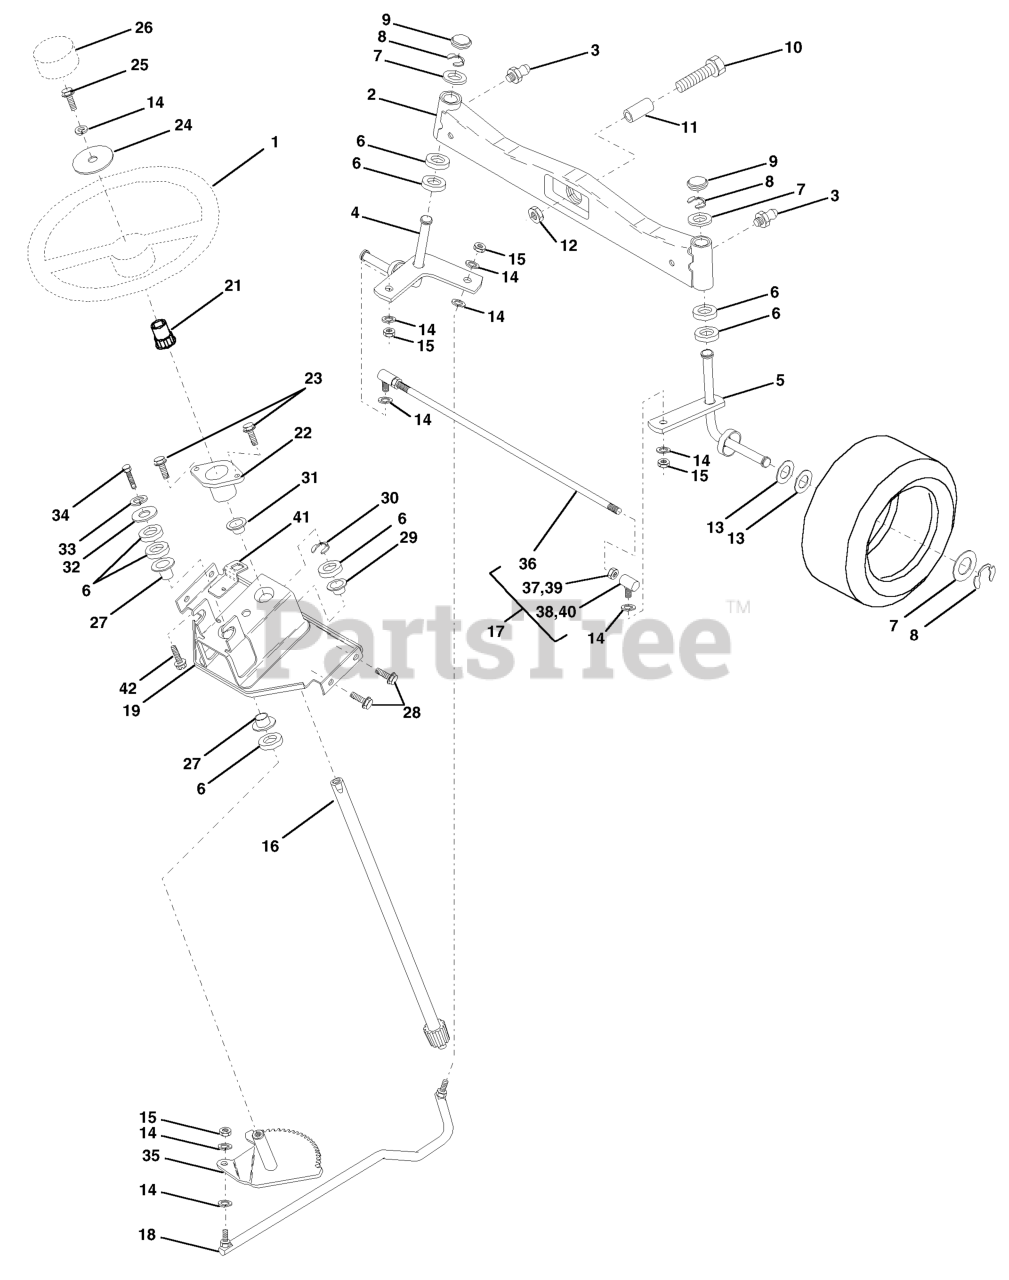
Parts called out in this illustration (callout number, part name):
1	STEERING WHEEL
2	FRONT AXLE ASSY
3	ZERK M
4	SPINDLE ASSY LH
5	SPINDLE ASM RH
6	THRUST WASHER
9	CAP.SPINDLE.BLACK
10	Bolt, Fin Hex 5/8-11 x 2-3/4
11	TUBE, PIVOT AXLE
12	NUT-LOC,FLANGE LT
14	WASHER, LOCK 3/8
15	GRIPCO NUT
16	SHAFT ASM, STEERING
17	ROD ASSY/TIE BALL
18	DRAGLINK-BALL JOINT SOLID
19	SUPPORT ASM., STEERING VGT
21	STEERING WHEEL ADAPTOR
22	BUSHING, STRG. BLK
23	SCREW.TT.#10-32X.5.3/8.FLANGE
24	Washer 13/32 x 1-1/20 x 11 Ga.
25	BOLT
26	CAP.WHEEL.STEERING.GREY
27	BRNG T
28	SCREW
29	BEARING-FLANGE GT
30	Ring, Klip Truarc #5304-75
31	BUSHING.NYLINER.
33	WASHER.LOCK.HVY.HLCL.SPR.5/16
34	BOLT
35	GEAR.ASM.SECTOR.
36	TIE ROD
38	JOINT
41	BRACKET INTERLOCK
42	Screw Thdrol 5/16-18 x 1/2 Tyt
